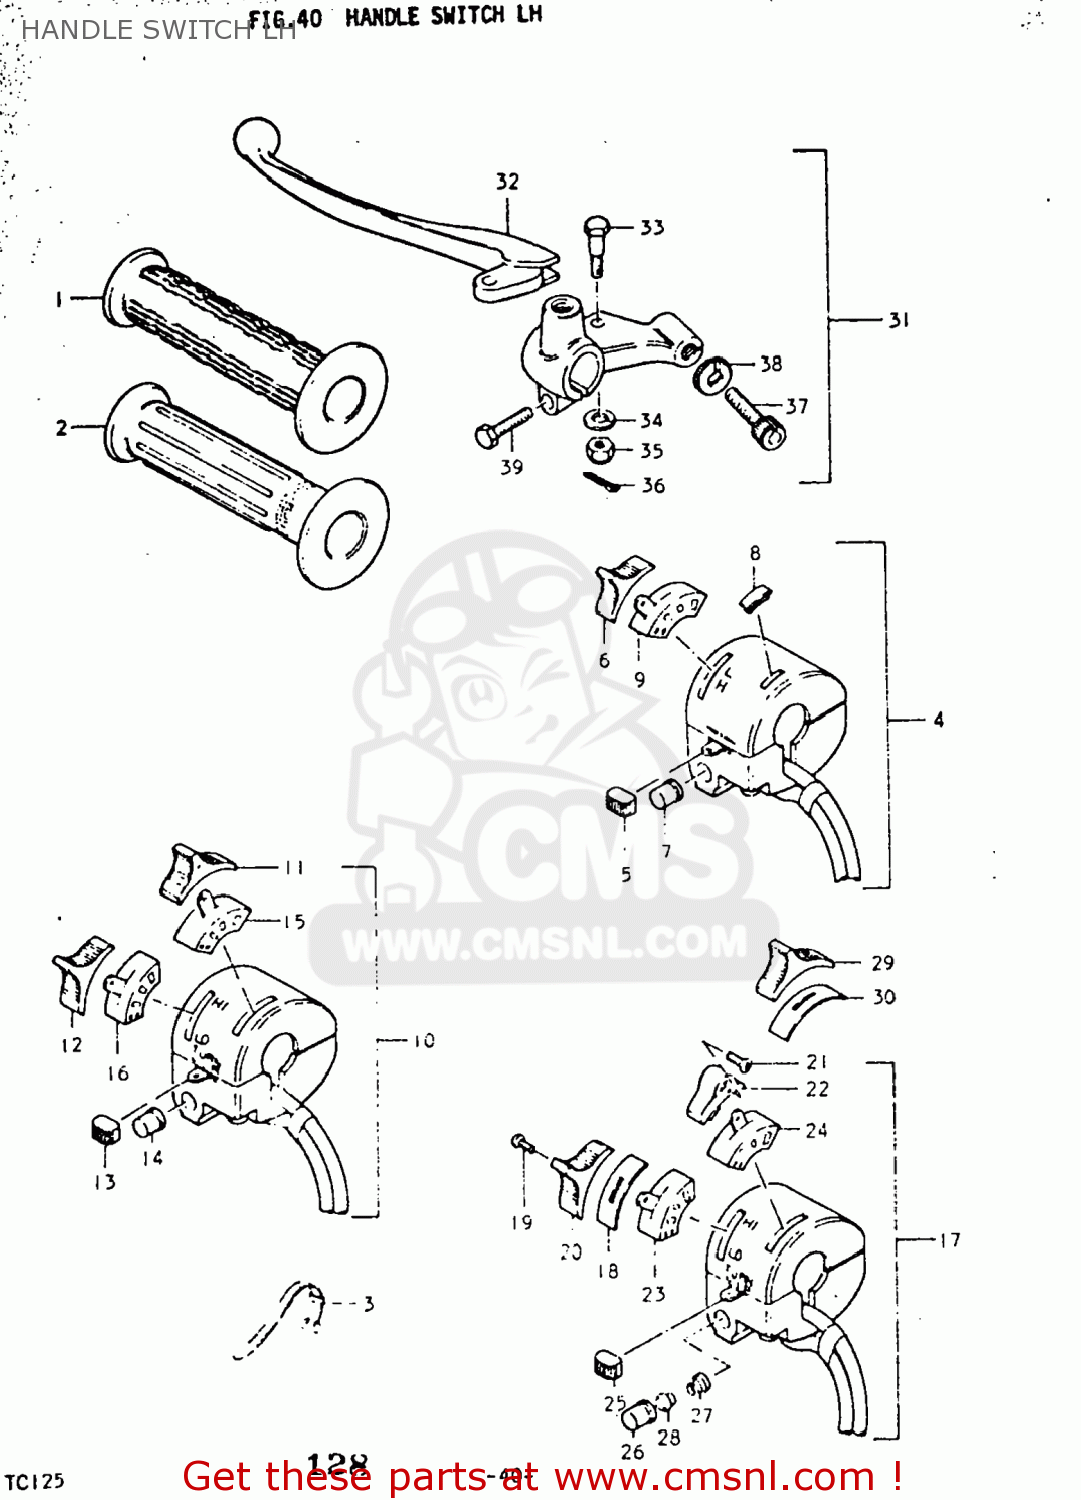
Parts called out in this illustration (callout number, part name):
1	GRIP
2	GRIP,L
3	CLAMP(L:120)
4	SWITCH ASSEMBLY,HANDLE
5	KNOB,HANDLE SWITCH
6	KNOB,HANDLE SWITCH
7	BUTTON, HORN
9	DIMMER SWITCH BLOCK
10	SWITCH ASSEMBLY,HANDLE
11	KNOB,HANDLE SWITCH
12	KNOB,HANDLE SWITCH,UPPER
13	KNOB,HANDLE SWITCH
14	BUTTON, HORN
16	SLIDING BLOCK, DIMMER SWITCH
17	SWITCH ASSEMBLY,HANDLE,LEFT
18	PLATE,DIMMER KNOB
19	SCREW, DIMMER
20	KNOB,HANDLE SWITCH,UPPER
21	SCREW
22	KNOB
23	SLIDING BLOCK, DIMMER SWITCH
25	KNOB,HANDLE SWITCH
26	BUTTON, HORN
27	SPRING,BUTTON
28	PLATE,HORN BUTTON
29	KNOB,HANDLE SWITCH
30	PLATE,LIGHTING KNOB
31	LEVER ASSEMBLY
32	LEVER,CLUTCH
33	BOLT,LEVER
34	LOCK WASHER
35	NUT,LEVER FITTNG
36	COTTER PIN
37	ADJUSTER,CABLE
38	NUT,CABLE ADJUSTER
39	BOLT
